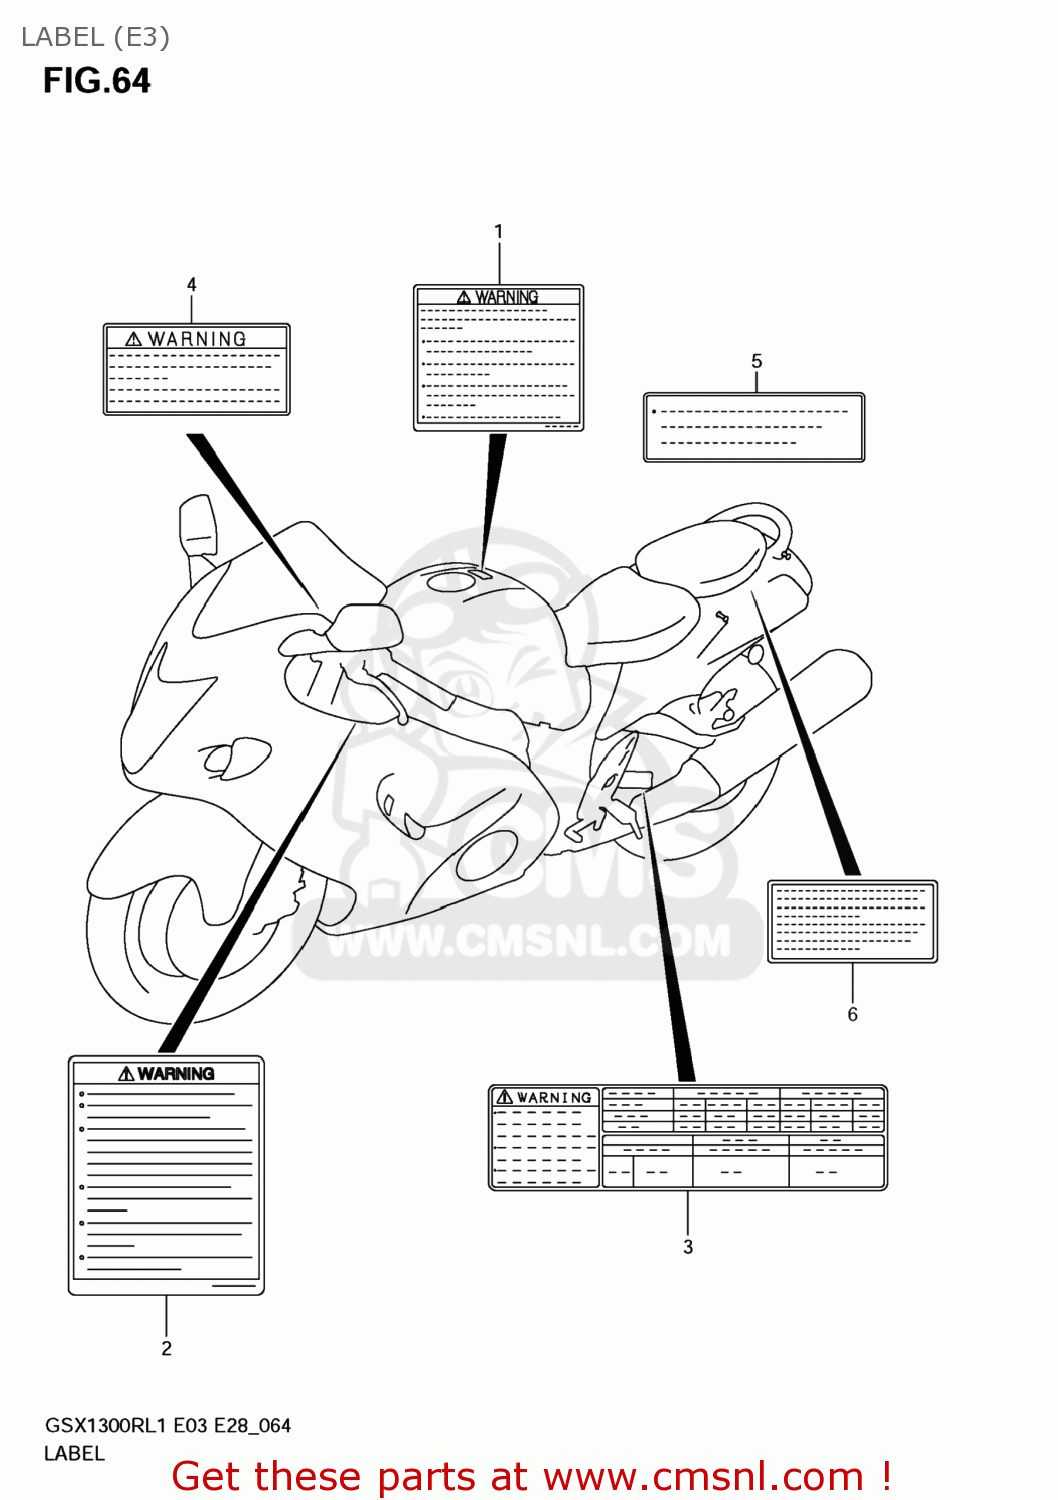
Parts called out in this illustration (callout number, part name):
1	LABEL,GENERAL WARNING
2	LABEL,SCREEN
3	LABEL,TIRE INFORMATION
4	LABEL,WARNING STEERING
5	LABEL,FUEL INFORMATION
6	LABEL,MANUAL NOTICE
7	MANUAL,SAFETY
8	MANUAL,OWNER'S
